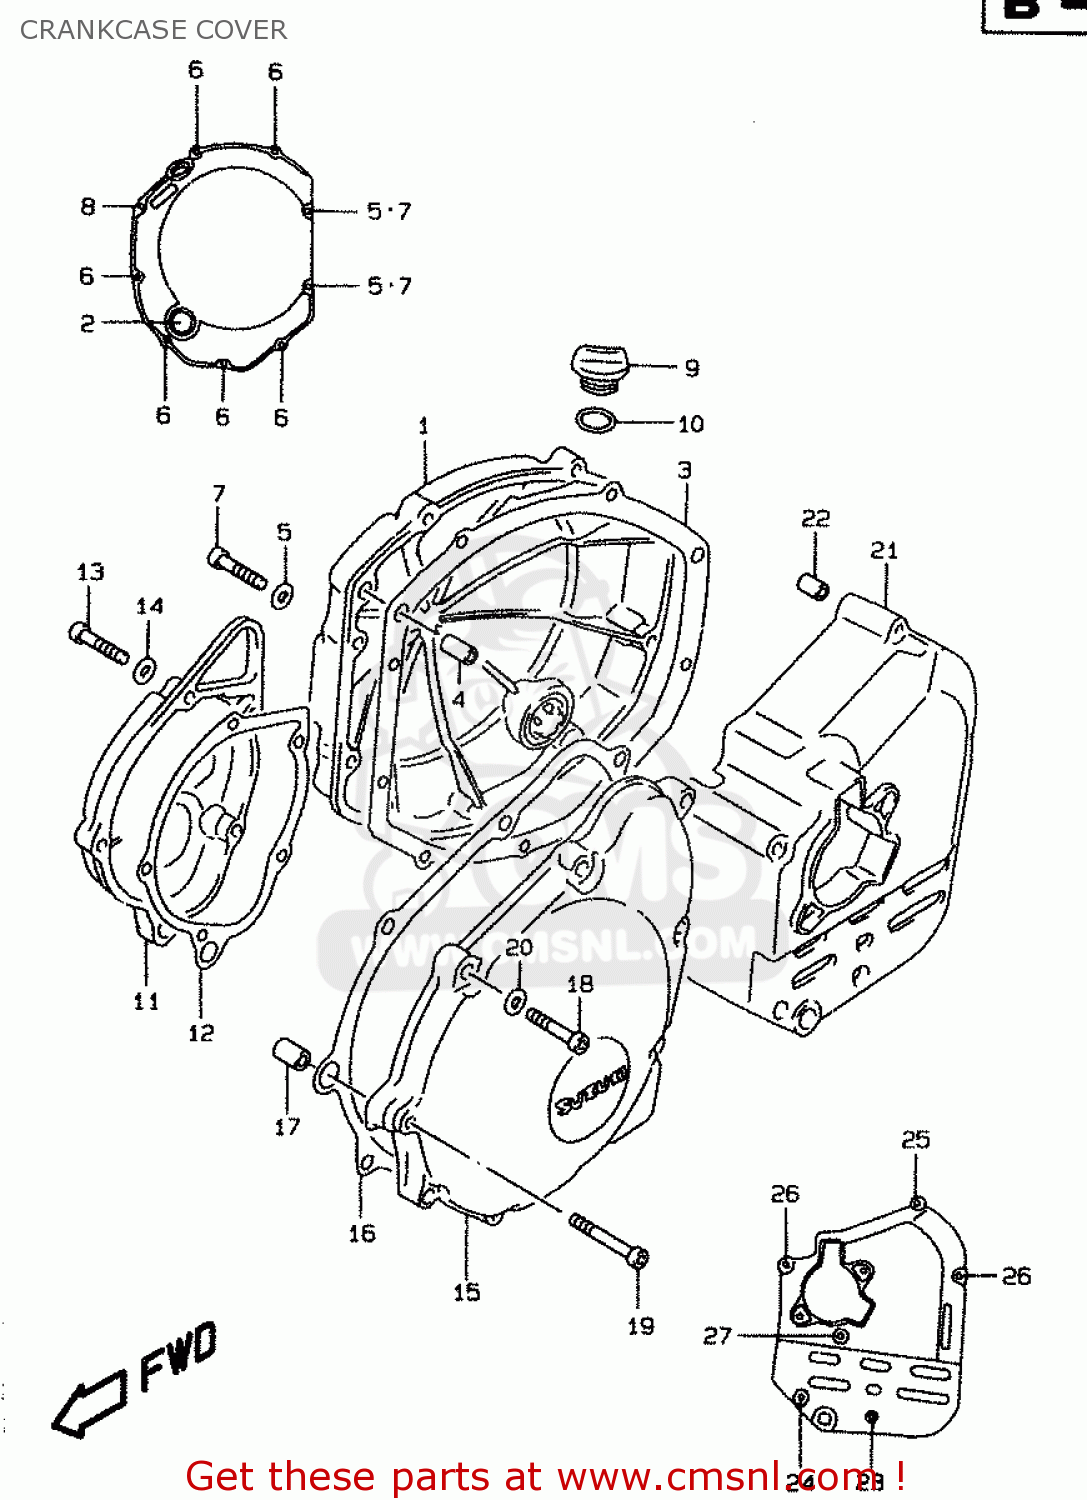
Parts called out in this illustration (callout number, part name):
1	COVER,CLUTCH
2	LENS,OIL LEVEL CHECK
3	GASKET,CL COVER (NAS)
4	PIN
5	GASKET(5.8X11X1.2) (NAS)
6	BOLT,CL.COVER
7	BOLT
8	BOLT
9	PLUG
10	O RING(D:3.1,ID:16.8)
11	COVER,SIGNAL GENERATOR
12	GASKET,SIGNAL GEN COVER (NAS)
13	BOLT(6X22)
14	GASKET(5.8X11X1.2) (NAS)
15	COVER,STARTER GEAR
16	GASKET,STARTER GEAR COVER (NAS)
17	PIN(8.4X11X20)
18	BOLT,CL.COVER
19	BOLT
20	GASKET(5.8X11X1.2) (NAS)
21	COVER COMP,ENGINE SPROCKET
22	PIN
23	BOLT
24	BOLT
25	BOLT
26	BOLT
27	BOLT
